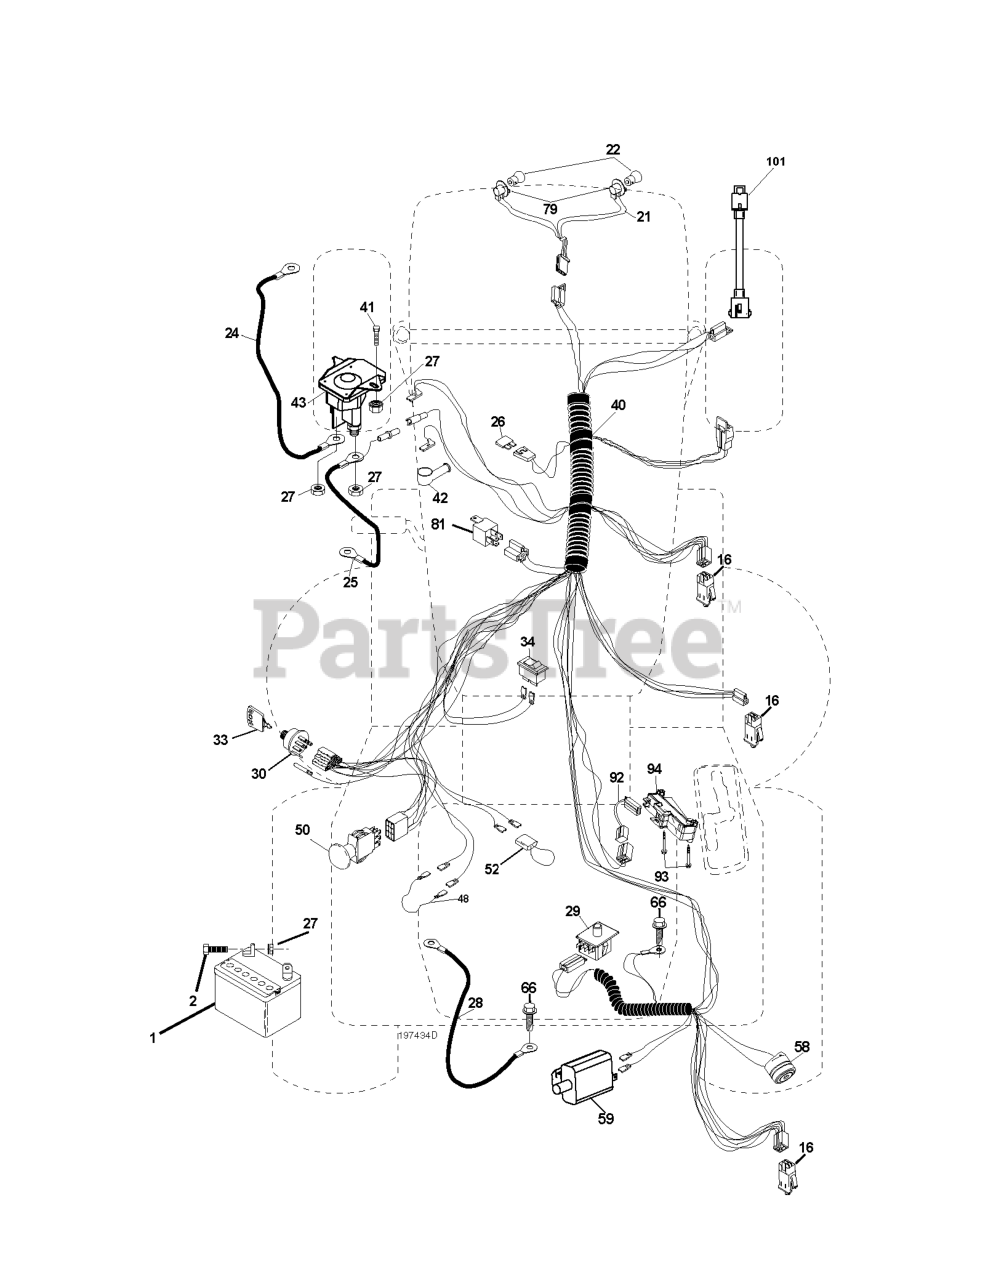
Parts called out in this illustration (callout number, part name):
1	BATTERY 12V .35 AMP
2	BOLT.HEX.1/4.X.3/4.DICHROMATE
16	SWITCH INTERLOOK PUSH-IN
21	HARNESS.LIGHT W/4152J BULBS
24	BATTERY CABLE GT
25	CABLE BATTERY
26	FUSE 20AMP
27	NUT
28	CABLE GROUND
29	SWITCH.SEAT.DP W/RAMPS
30	SWITCH.IGN.DELTA.W.LGH.ROS
33	KEY MLD GEN DELTA
40	RP HARNESS.IGN.ELECT.REG.CRD
41	BOLT
42	TERMINAL COVER
43	SOLENOID.W/BRASS.PLUNGER
48	ADAPTER.AMMETER
50	RP.PTO.SWITCH.8 TERMINAL.BLACK
52	WIRE PROTECTION LOOP
58	BUZZER
59	.WITCH.FULL BAGGER.INDICATOR
79	BULB HOLDER ASM.
81	RELAY.ASSY.T
92	HARNESS.PIGTAIL.CONSLE
93	SCREW.PLASTITE
94	MODULE.REVERSE.ROS
101	PIGTAIL.MATNLK.NEW.HAR
